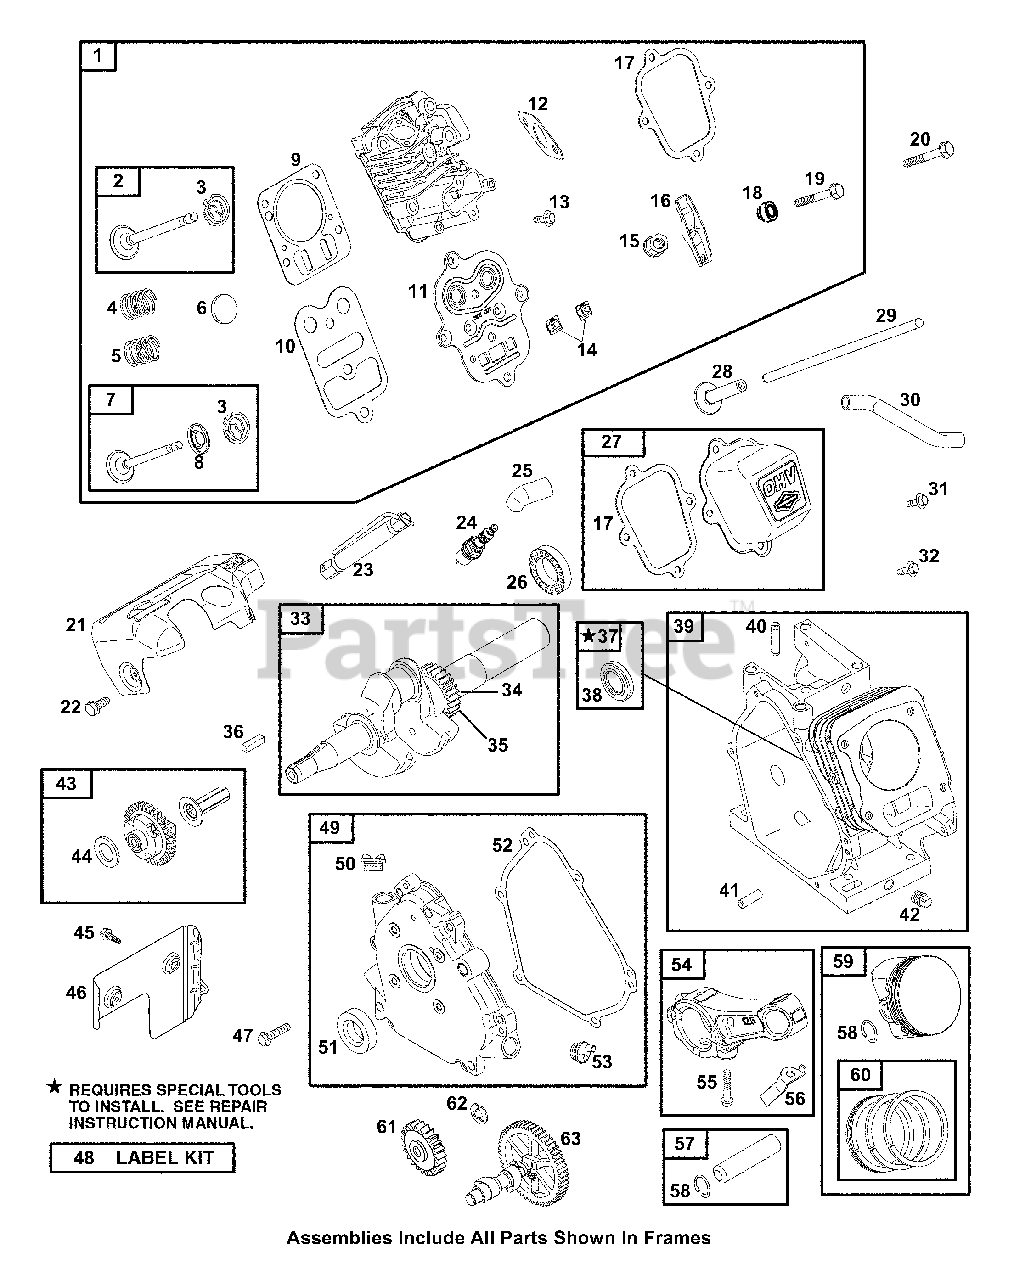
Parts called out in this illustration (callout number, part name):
1	Cylinder Head
2	Exhaust Valve
3	Valve Retainer
4	Valve Spring (Intake)
5	Valve Spring (Exhaust)
7	Intake Valve
8	Seal-Valve
9	Cylinder Head Gasket
10	Cylinder Head Plate Gasket
11	Cylinder Head Plate
12	Intake Gasket
13	Screw (Cylinder Head Plate)
14	Guide-Push Rod
15	Nut (Rocker Arm)
16	Rocker Arm
17	Gasket-Rocker Cover
18	Rocker Arm Ball
19	Screw (Rocker Arm)
20	Screw (Cylinder Head)
21	Shield-Cylinder
22	Screw (Cylinder Shield)
23	Wrench-Spark Plug
24	Sparkplug
25	Boot-Spark Plug
26	Ball Bearing
27	Cover-Rocker
28	Valve Tappet
30	Breather Tube
31	Screw (Rocker Cover 3/8" Long)
32	Screw (Rocker Cover 7/16" Long)
33	Crankshaft
34	Timing Key
35	Gear-Timing
36	Flywheel Key
37	Bushing/Seal Kit
38	Oil Seal
39	Cylinder Assembly
40	Bushing-Governor Crank
41	Pin-Locating
42	Oil Drain Plug
43	Governor Gear
44	Washer (Governor Gear)
45	Screw (Panel)
47	Screw (Crankcase Cover)
49	Cover-Crankcase
52	Crankcase Gasket
53	Oil Fill Cap
54	Connecting Rod
55	Screw-(Connecting Rod)
56	Connecting Rod Dipper
57	Piston Pin
58	Piston Pin Lock
59	Piston Assembly (Standard)
60	Ring Set (Standard)
61	Gear-Idler
62	Ring-Retaining
